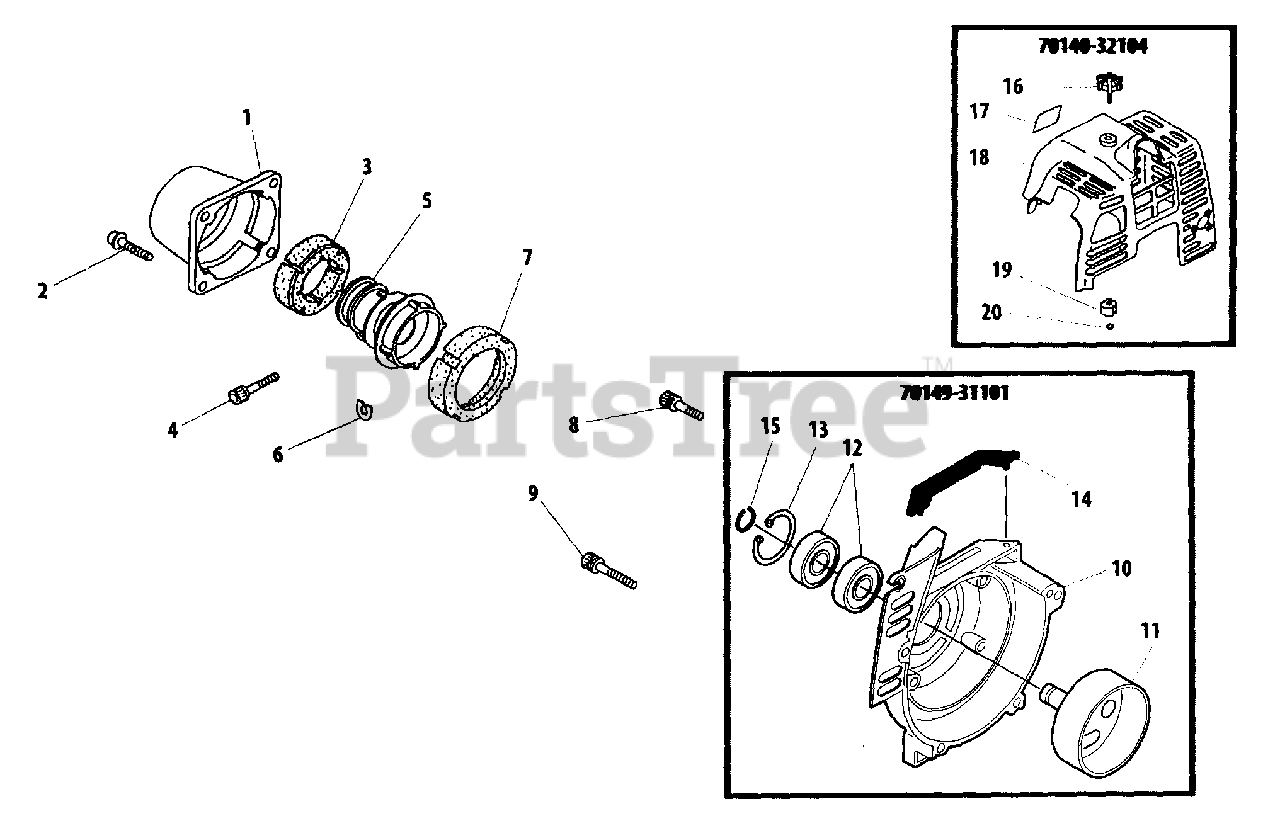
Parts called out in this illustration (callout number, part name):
1	COVER, AV CUSHION (RED)
2	BOLT M5×16
3	CUSHION, FRONT
4	BOLT M5×25
5	JOINT
6	D-WASHER
7	HOLDER, REAR CUSHION
8	BOLT M5×16
9	BOLT M5×35
10	COVER, FAN
11	DRUM, CLUTCH
12	BEARING, BALL 6000ZZ
13	RING, SNAP Ø26
14	CUSHION
15	RING, SNAP WR10
16	THUMBSCREW
17	LABEL
18	COVER, ENGINE
19	INSULATOR 5 MM
20	CLIP
70140-32104	ENGINE COVER KIT - RED
70149-31101	FAN CASE ASSY
